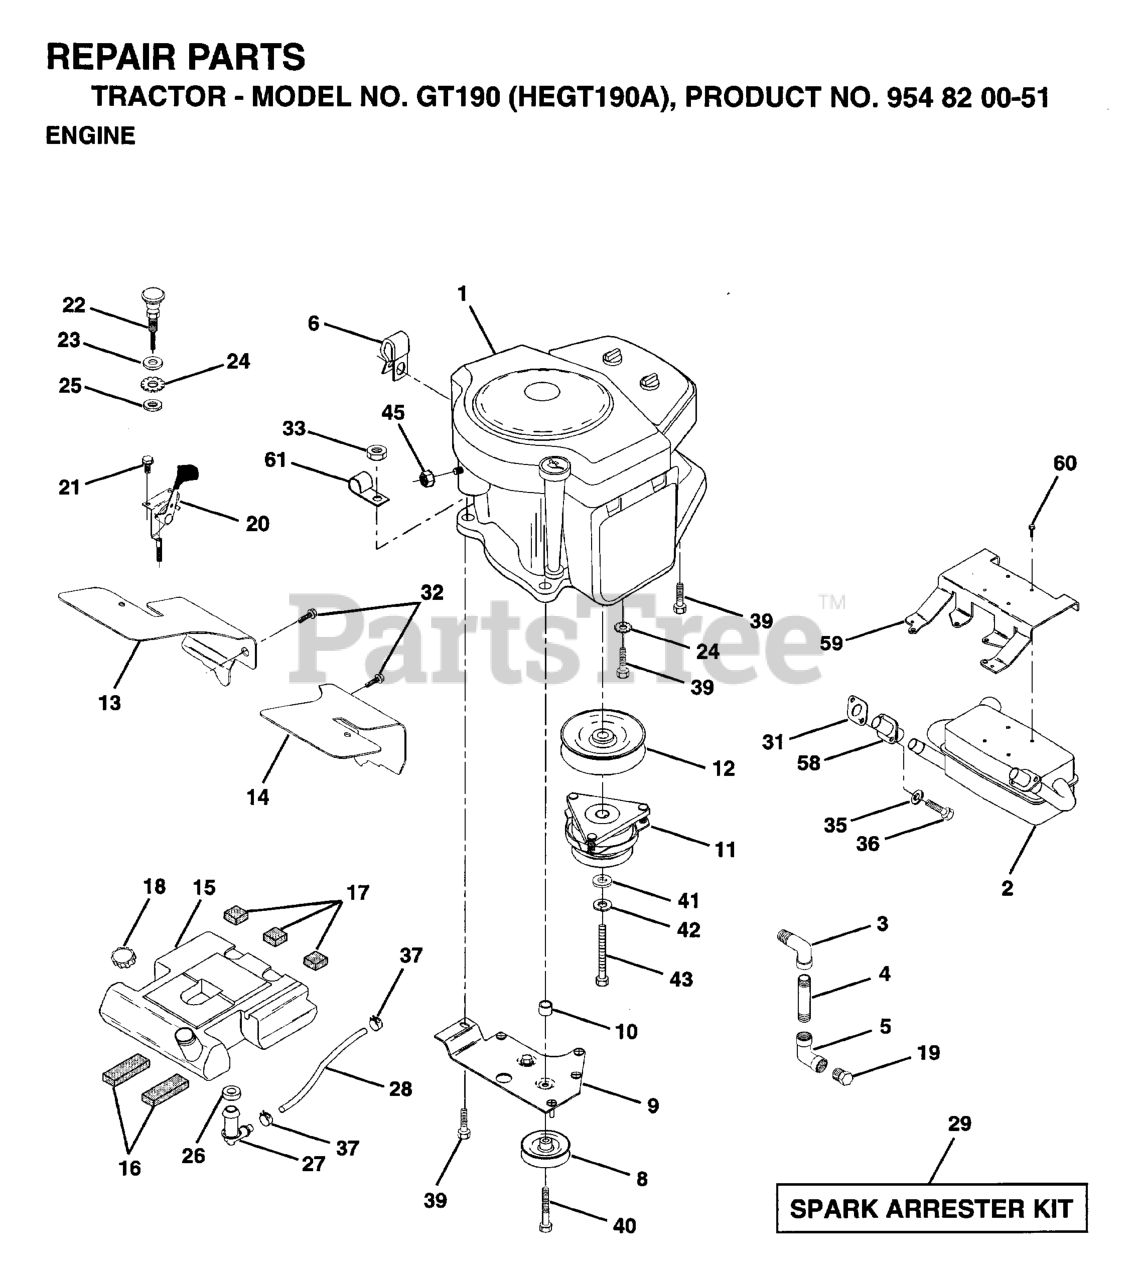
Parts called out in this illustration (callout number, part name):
5	90° Elbow, 3/8 NPT
17	Pad, Spacer
21	Screw Hex Washer Head Thread Cutting 1/4 - 20 x 1/2
23	Washer 13/32 x 13/16 x 16 Gauge
24	Washer, Lock, Int/Ext. Tooth 3/8
25	Nut, Hex 3/8-24
32	Screw Thdrol 5/16-18 x 1/2
33	Lockout, Hex w/Washer Insert 3/8-16 UNC
35	Washer, Lock, Heavy Helical Spring
37	Clamp, Hose
39	Screw, Hex Washer Head, Thd. Roll. 3/8-16 x 1-1/2 Type TT
41	Washer 1-1/2 x 15/32 x 1/4
42	Washer, Lock 7/16
43	Bolt, Hex, Fin 7/16-20 UNF x 4-1/4 Grade 8
45	NUT FLANGE 1/4-20 STARTER NUT
60	Screw, Hex Wash Thdcut 1/40-20 UNC
61	Clip, Fuel Line
